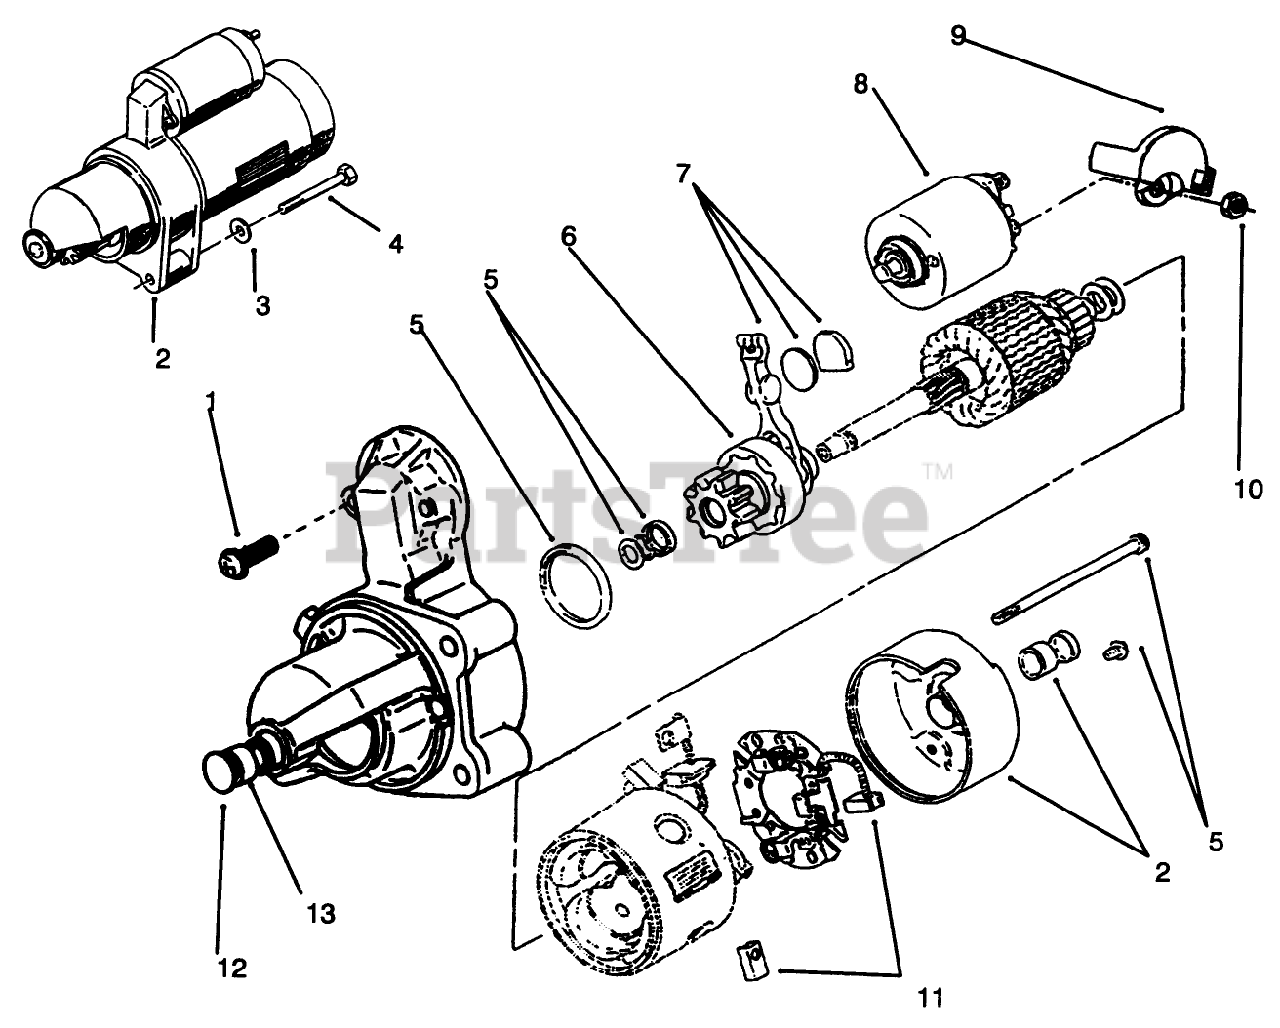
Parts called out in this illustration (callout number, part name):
3	WASHER
10	HEX NUT
12	BUSHING
13	KIT-MTG BRKT
